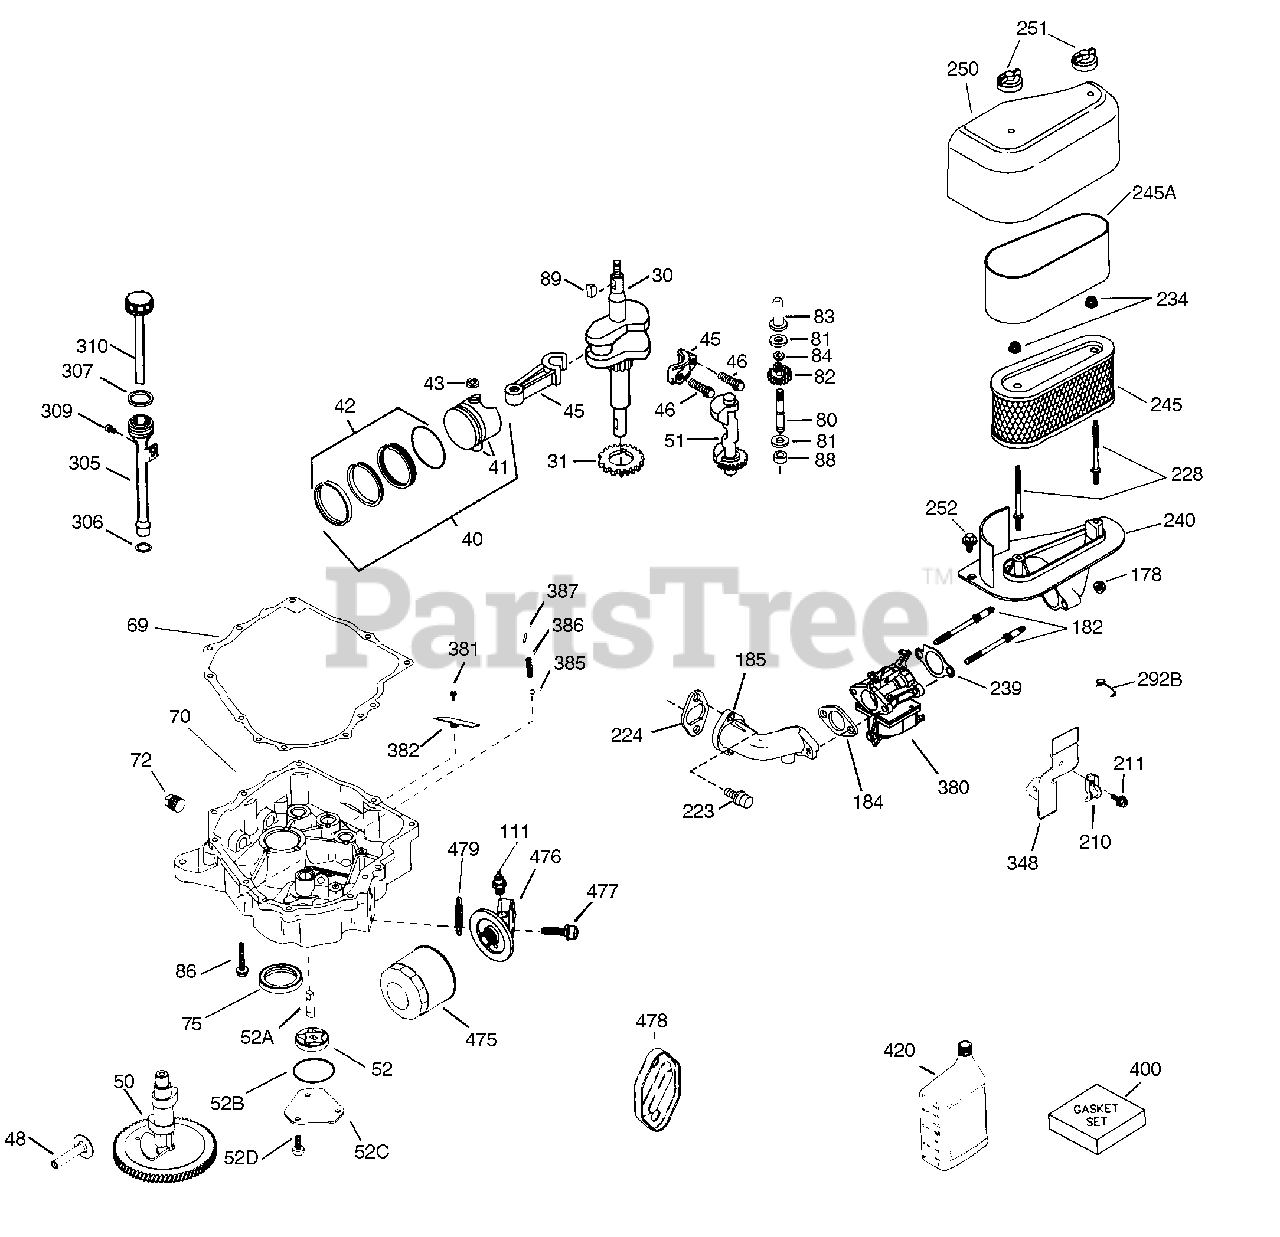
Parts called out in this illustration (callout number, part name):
30	Crankshaft
31	Counterbalance Gear
40	Piston, Pin & Ring Set (Std) (Incl. 4 1, 42 & 43)
40	Piston, Pin & Ring Set (.010" OS) (In cl. 41, 42 & 43)
40	Piston, Pin & Ring Set (.020" OS) (In cl. 41, 42 & 43)
41	Piston & Pin Assembly (Std) (Incl. 43 )
41	Piston & Pin Ass'y. (.010" OS) (Incl. 43)
41	Piston & Pin Ass'y. (.020" OS) (Incl. 43)
42	Ring Set (Std.) (3-5/16")
42	Ring Set (.010" OS)
42	Ring Set (.020" OS)
43	Piston Pin Retaining Ring
45	Connecting Rod Ass'y. (Incl. 47)
47	Connecting Rod Bolt
48	Valve Lifter
50	Camshaft (MCR)
51	Counterbalance Weight
52	Oil Pump Ass'y.
62	Screw, 8-32 x 3/8"
63	Breather Tube Grommet
68	Ground Terminal
69	* Mounting Flange Gasket
70	Mounting Flange (Incl. 72, 72A, 75 & 80)
72	Oil Drain Plug
75	Oil Seal
80	Governor Shaft
81	WASHER
82	Governor Gear Assembly
83	Governor Spool
84	Retaining Ring
86	Screw, 1/4-20 x 1-3/16"
89	Flywheel Key
123	Intake Pipe Brace
124	Screw, 1/4-20 x 9/16"
182	Screw, 1/4-20 x 27/32"
184	* Carburetor To Intake Pipe Gasket
185	Intake Pipe
186A	Choke Link
210	Conduit Clip
211	Screw, 10-32 x 3/8"
223	Screw, Torx T-30, 5/16-18 x 7/8"
224	* Intake Pipe Gasket
234	Nut & Lock Washer, 1/4-20
237	Air Filter Adapter
238	Screw, 10-32 x 5-1/4"
239	* Air Cleaner Gasket
240	Air Cleaner Body (Incl. 239)
245	Air Filter (Incl. 234) also available in Packaged Part #740015B
245A	Pre-Cleaner Air Filter also available in Packaged Part #740015B
250	Air Cleaner Cover
251	Wing Nut, 1/4-20
261	Screw, T-30, 1/4-20 x 1/2"
264A	Screw, T-30, 1/4-20 x 1/2"
266	Screw, 5/16-18 x 1-1/4"
269	* Exhaust Manifold Gasket
270	Exhaust Manifold
271	Locking Plate (Manifold)
275	Muffler
276	Locking Plate
305	Oil Fill Tube
307	"O" Ring
308	Fill Tube Clip
308A	Fill Tube Clip
310	Dipstick
325A	Wire Clip
337	Deflector
370G	Decal - Important Lubrication - SAE 3
370R	Warning Decal
380	Carburetor (Incl. 184)
393	Cup & Screen
400	* Gasket Set (Incl. items marked PK in notes) Incl. part #'s 27896 (2), 332 63 (1), 33629 (2), 34265 (1), 35317 ( 1), 35762 (2), 35946 (1), 35352 (1), 35958 (1)
414	Spark Arrestor Screen (Incl. 417)
900	Replacement Engine None
900	Replacement Short Block 752321, order from 71-999
